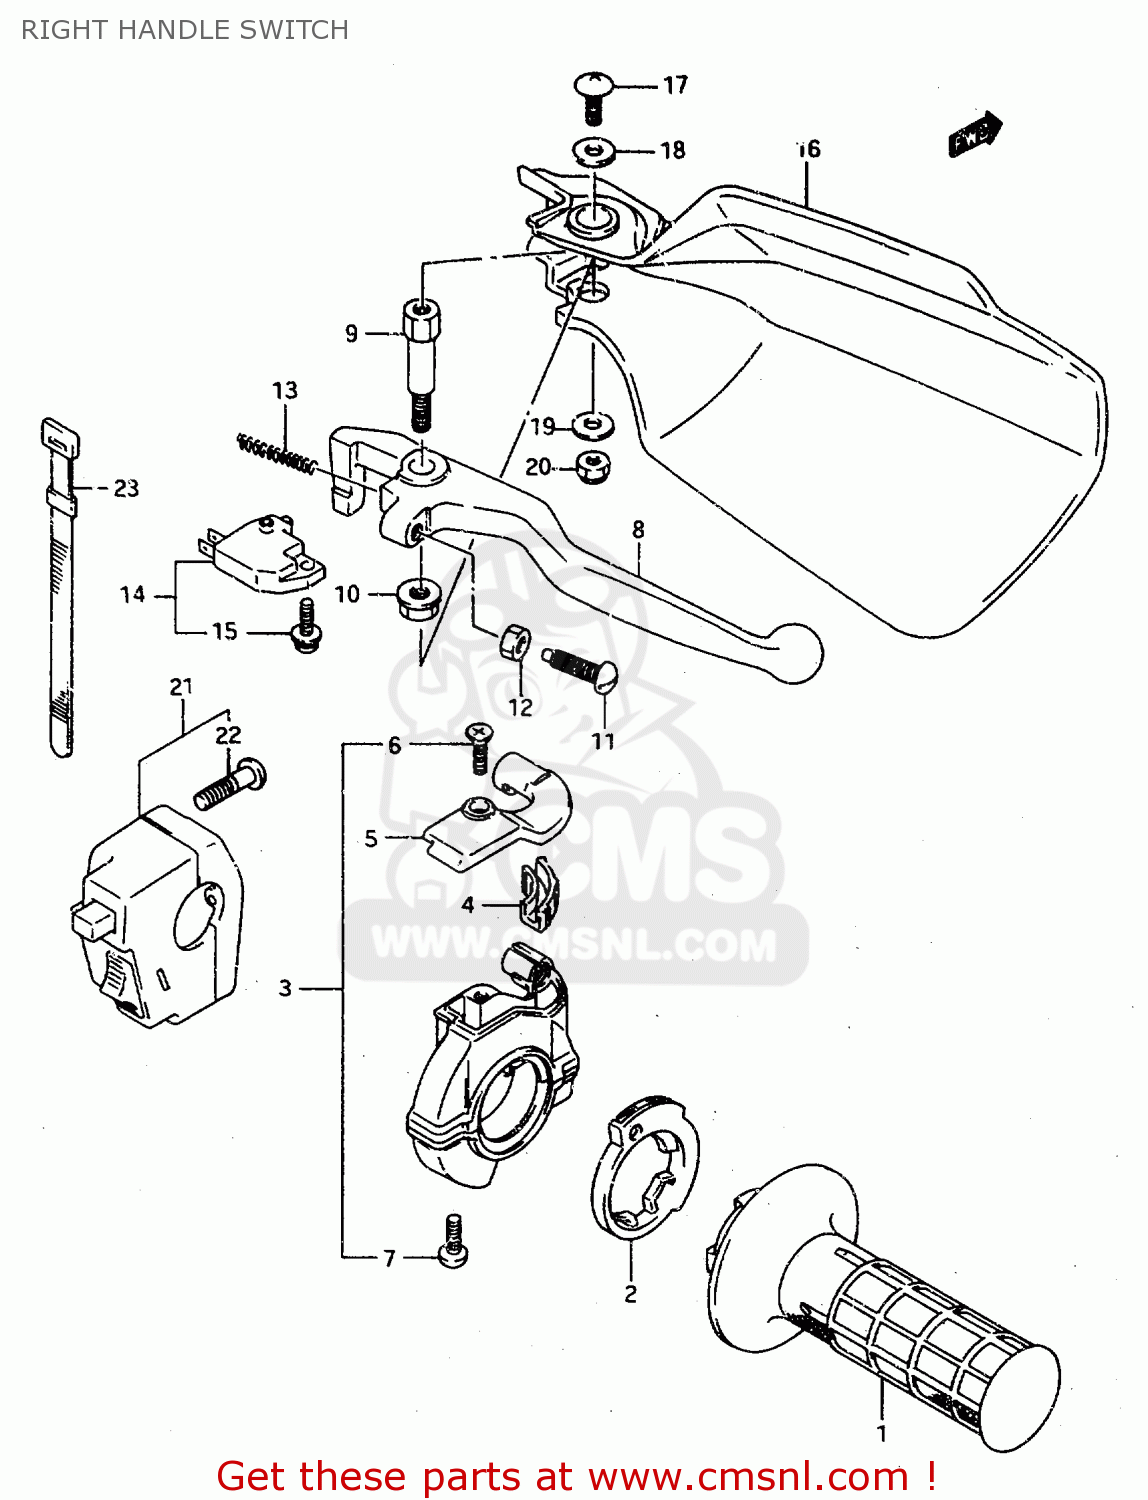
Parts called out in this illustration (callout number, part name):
1	GRIP,THROTTLE
2	ROTOR,THROTTLE GRIP
3	CASE ASSY,THROTTLE
4	GUIDE PIECE,THROTTLE
5	COVER,THROTTLE CASE
6	SCREW 4X10
7	SCREW
8	LEVER,BRAKE
9	BOLT,BRAKE LEVER PIVOT
10	NUT 6MM
11	BOLT,ADJUST
12	NUT ,5MM
13	SPRING,RETURN
14	SWITCH ASSEMBLY,STOP
15	SCREW
16	COVER,KNUCKLE,R
17	SCREW
18	WASHER (5.5X16X1.2)
19	WASHER (6.5X17X1.6)
20	NUT 6MM
21	SWITCH ASSY, HANDLE, RH
22	SCREW(5X25)
23	CLAMP(L:120)
